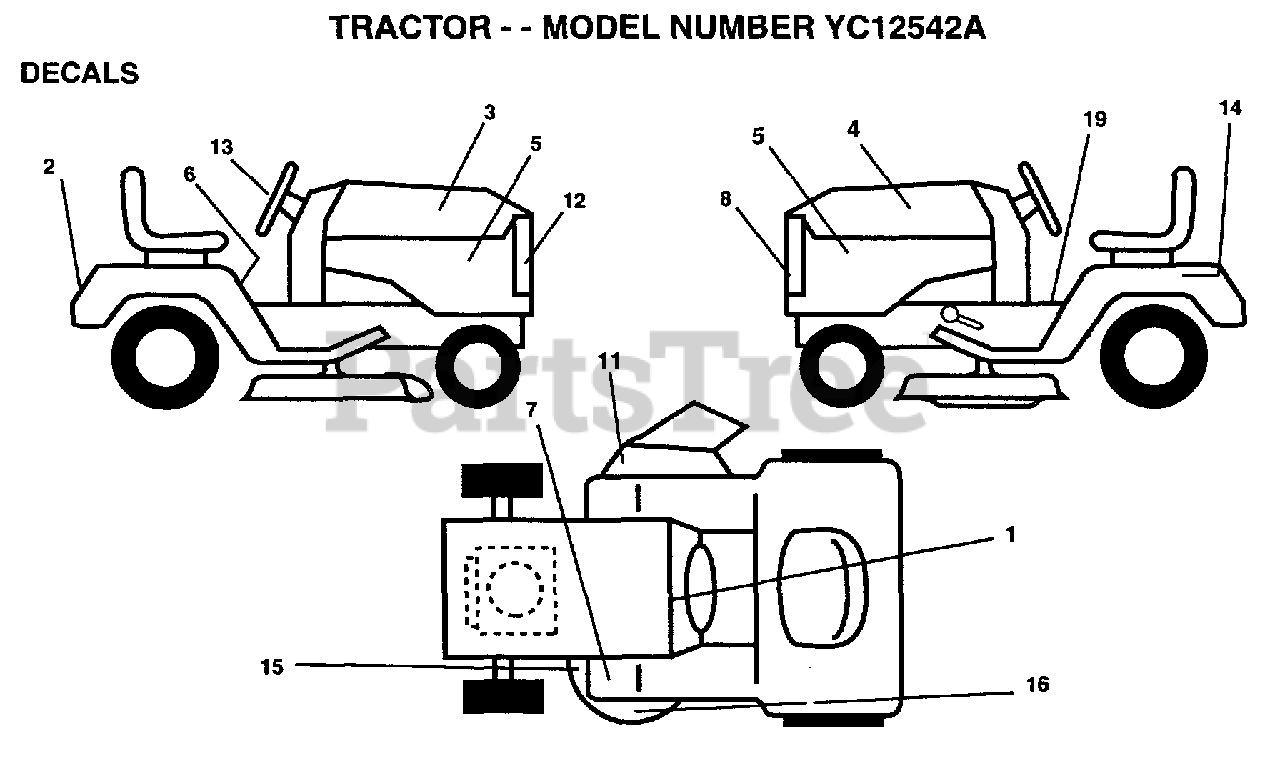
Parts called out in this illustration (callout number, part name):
1	DECAL.DASH.INSTR.
5	DECAL.PANEL.SIDE
6	DECAL CAUTION
7	DECAL T
11	"DECAL, WARNING"
12	DECAL.GRILL.YARDP
13	DECAL.INSERT.STRG
14	DECAL
15	DECAL
19	DECAL BRAK PARK
